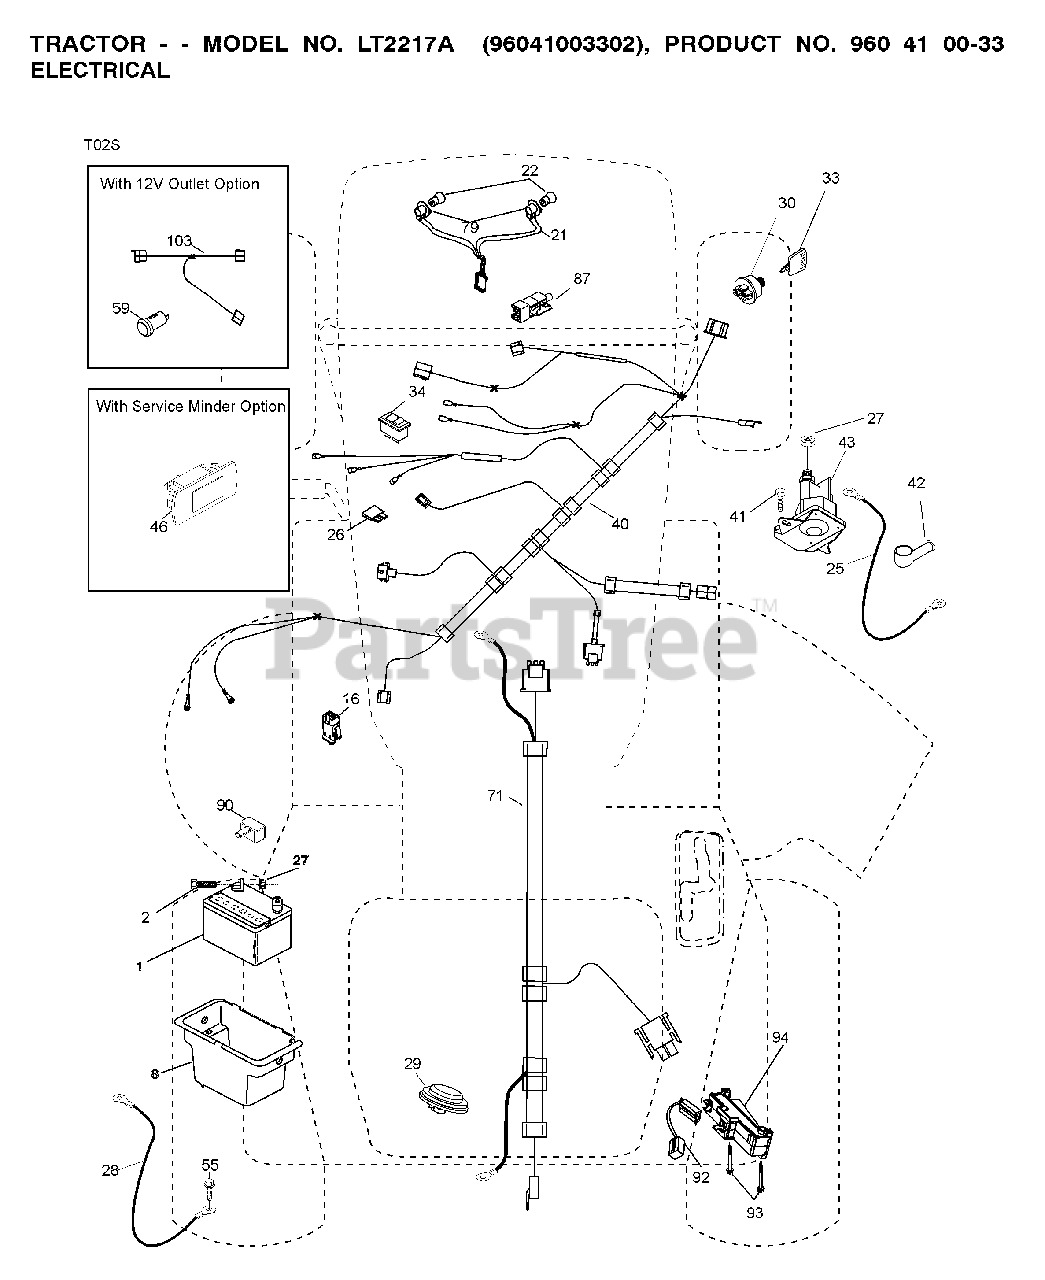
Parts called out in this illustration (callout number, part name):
1	REPL BY 532 12 38-99
8	BOX.BATTERY.MNT.REAR.L
16	SWITCH INTERLOOK PUSH-IN
21	HARNESS ASSY LIGHT
22	LIGHTBULB
25	CABLE.STARTER.6GA.RED.
26	FUSE 20AMP
27	NUT
28	CABLE.BLACK.18"REAR.BA
29	SWITCH.SEAT.DELTA.OPC.
30	SWITCH.IGN.DELTA.W.LGH.ROS
33	KEY.CHAIN.BLISTER.PACK.GEN.INT
34	SWITCH LT
40	HARNESS IGN. DASH
41	SCREW
42	TERMINAL COVER
43	SOLENOID.W/BRASS.PLUNG
55	SCREW 5/16"
71	HARNESS.IGN.CHASS.TEX.REAR.BAT
79	BULB HOLDER ASM.
87	SWITCH.INTRLCK.CLUTCH.
90	COVER, TERMINAL BATTERY
92	HARNESS.PIGTAIL.CONSLE
93	SCREW.PLASTITE
94	MODULE.REVERSE.ROS
